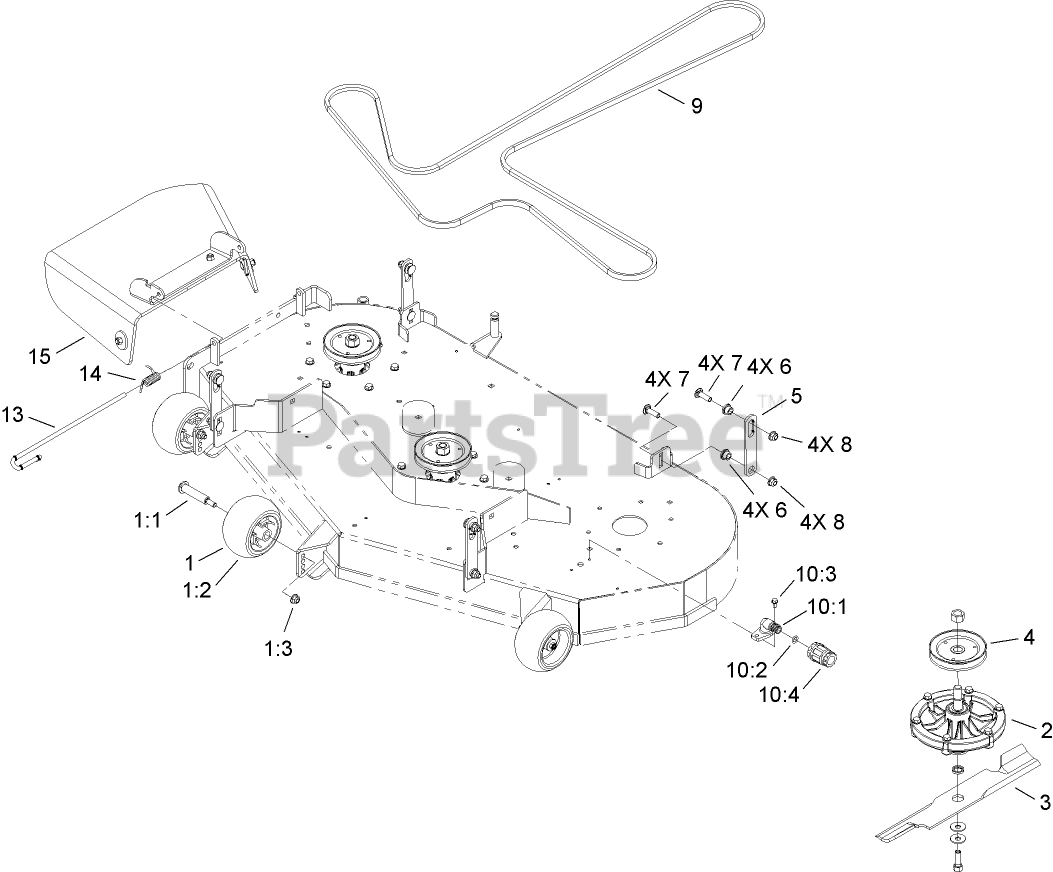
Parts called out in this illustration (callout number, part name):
1	ANTI-SCALP ROLLER KIT
1:1	BOLT-SHOULDER
1:2	ROLLER-SCALP, ANTI
1:3	NUT-HF, NI
3	BLADE-NOTCHED
5	HANGER-DECK
6	SPACER-STRUT
7	BOLT-CARR
8	NUT-HF, NI
9	BELT
10:2	O-RING
10:3	SCREW-HWH
10:4	CONNECTOR-HOSE
14	SPRING
15	RUBBER DEFLECTOR ASM
